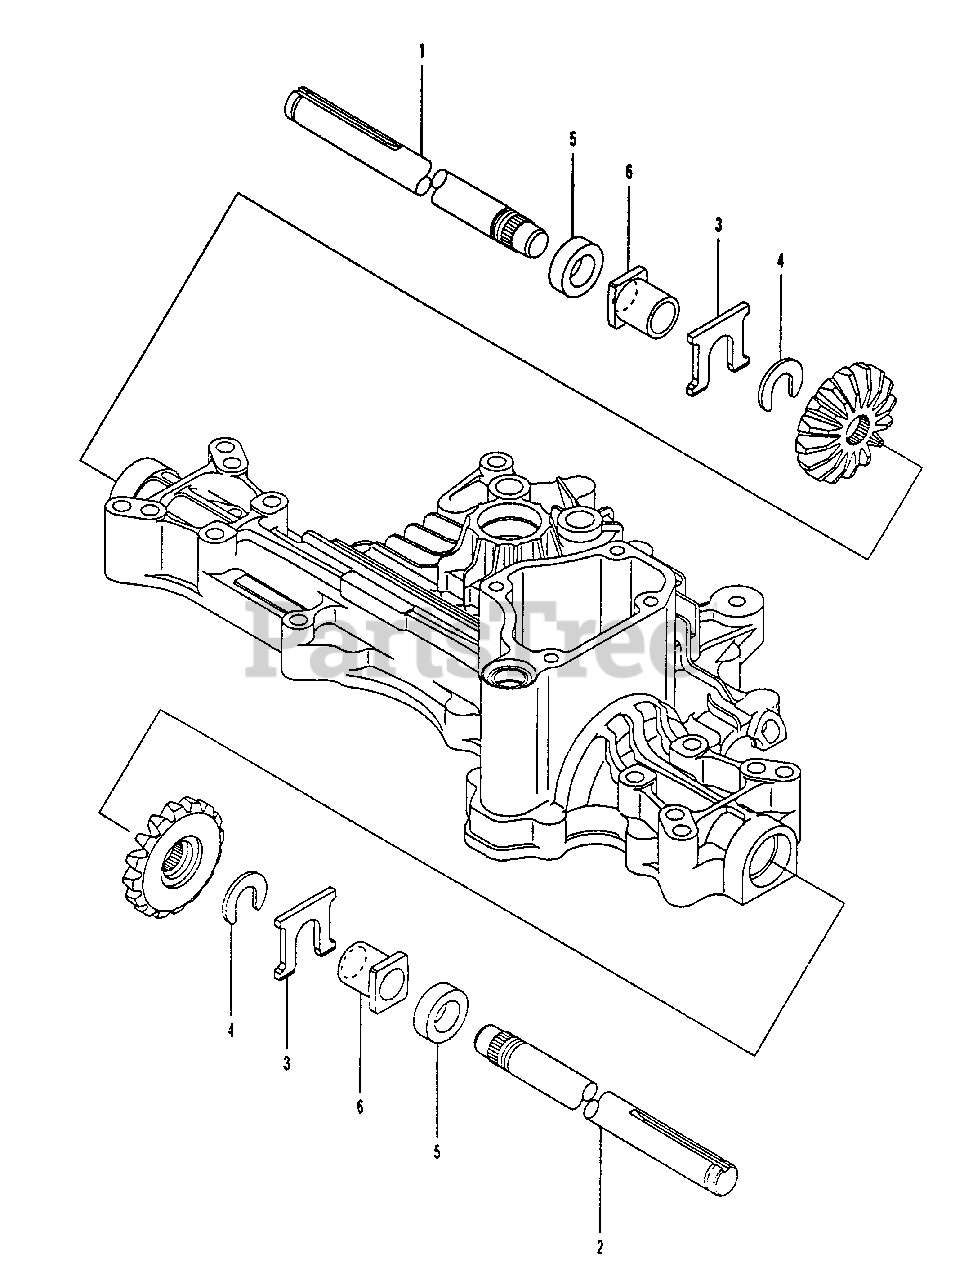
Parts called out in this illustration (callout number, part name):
1	AXLE SHAFT L
2	AXLE SHAFT R
3	THRUST WASHER
5	SEAL (S 19 X 32 X 8
6	BUSHING 19 X 25
